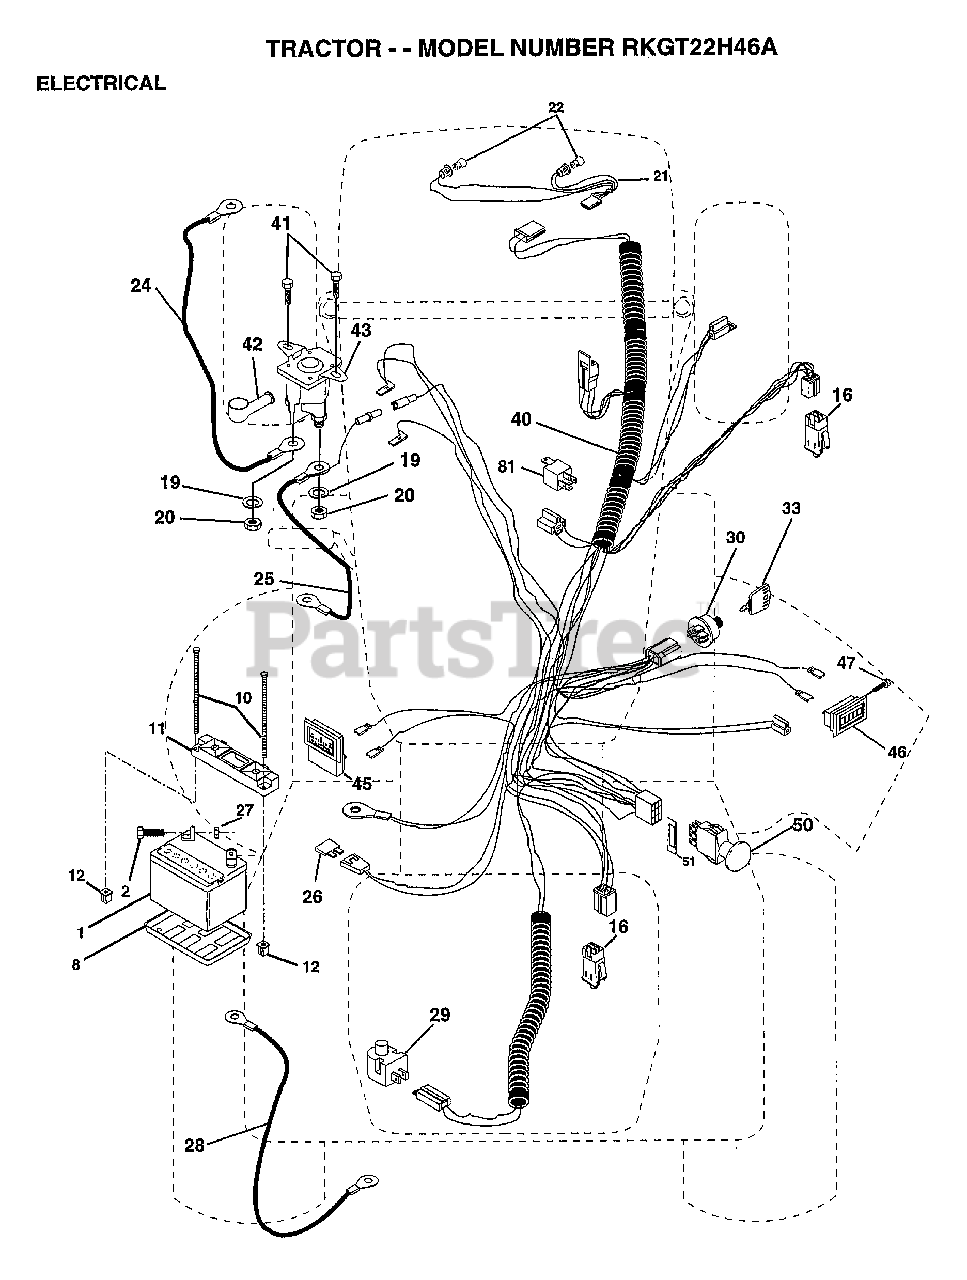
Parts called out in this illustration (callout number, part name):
2	BOLT LT
8	"TRAY T, BATTERY"
11	HOLDDOWN BATTERY
16	SWITCH INTERLOCK
20	NUT
21	HARNESS.ASM.LIGHT.W/4152J
22	HEADLAMP BULB
24	CABLE.BATY.22.RED
25	CABLE.BATRY.4GA.
26	FUSE HYT
27	NUT
28	"CABLE BATTERY,GRD"
29	SWITCH.PLUNGER
30	SWITCH.IGN.
33	KEY MLD GEN DELTA
40	HARNESS.IGN.
41	SCREW
45	AMMETER
46	HOUR METER T
47	SCREW
50	PTO SWITCH.BLK
51	RING RETAIN PTO
81	RELAY ASSY T
